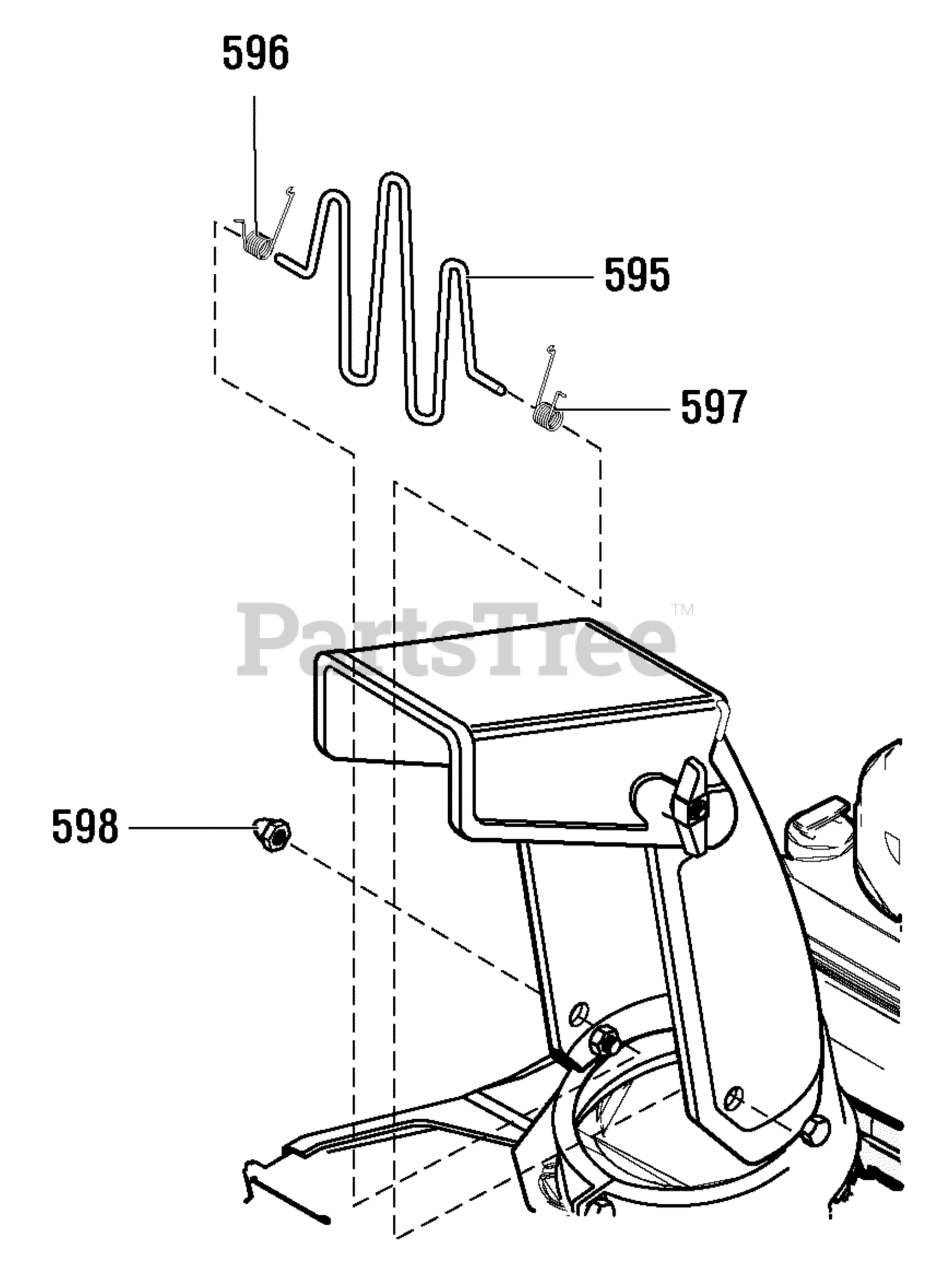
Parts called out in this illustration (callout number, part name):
595	GUARD, WIRE CHUTE
596	SPRING, TORSION
597	SPRING, TORSION
598	NUT, ACORN
